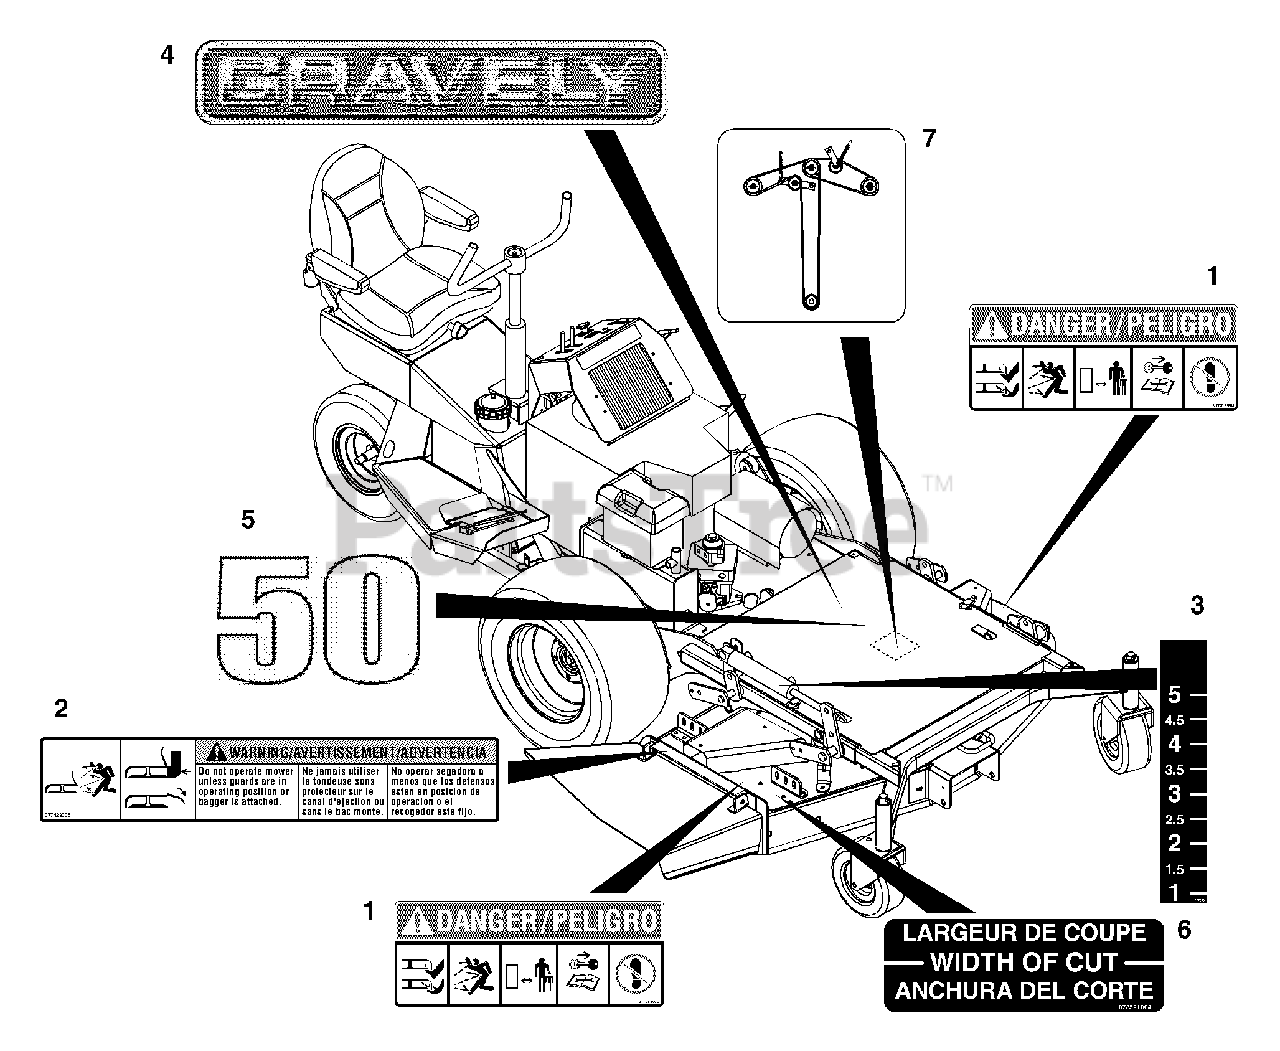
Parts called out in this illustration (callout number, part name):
1	Decal, Mower Pan Head Danger
2	Decal, Warning
3	Decal, Width of Cut
4	Decal-15" Gravely Logo
5	Decal, 50
5	Decal, 60
5	Decal, 72
6	Decal, Height of Cut
7	Decal, Belt Diagram
